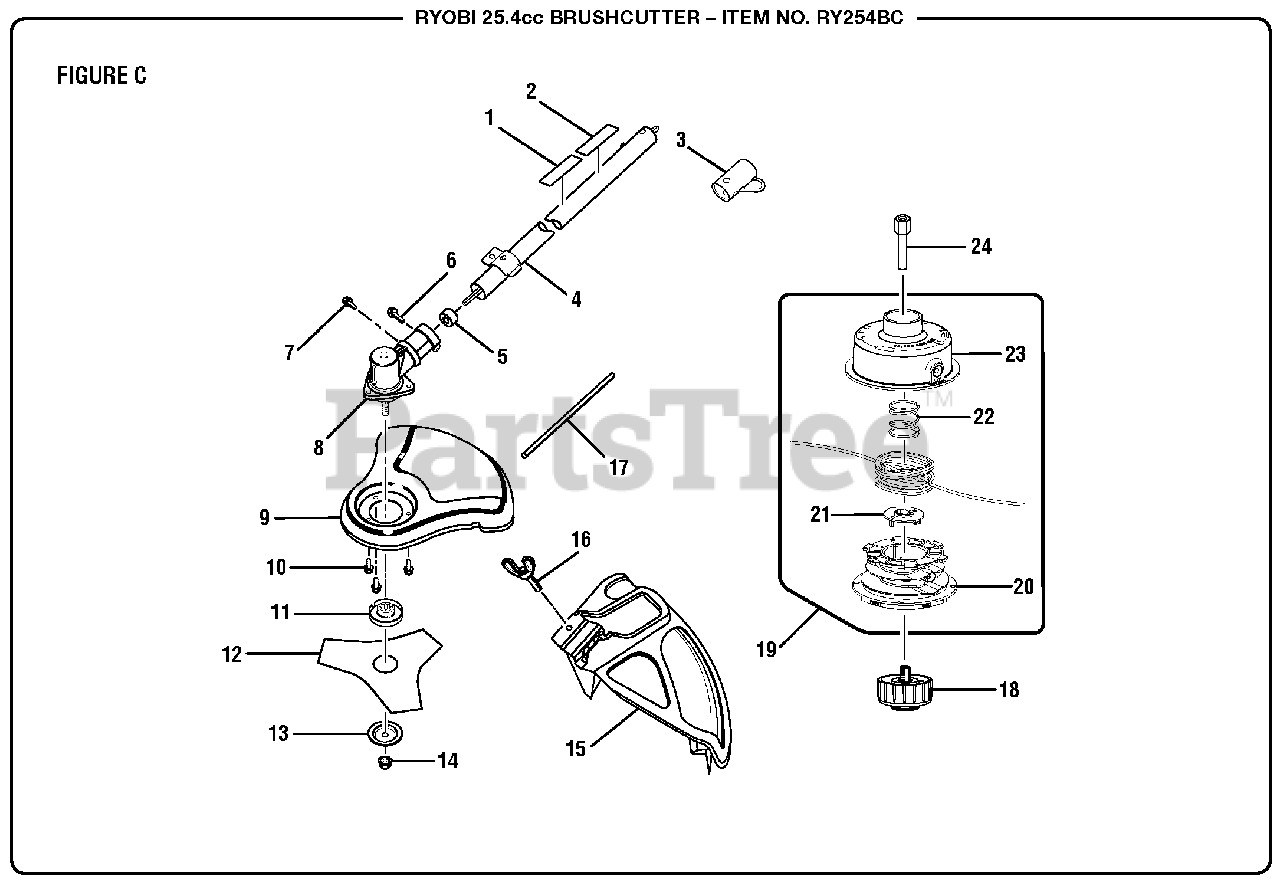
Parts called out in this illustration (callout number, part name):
1	Expand-it Label
2	Brushcutter Safety Label
3	Storage Hanger Cap
4	Lower Straight Shaft Boom Assembly
6	Screw (1/4-20 x 1-1/4 in., Hex Washer Hd. S.T.)
7	Screw (10-24 x 5/8 in., Hex Washer Hd. S.T.)
8	Gear Case Assembly
9	Brushcutter Guard
10	Screw w/Washer (10-24 x 1/2 in., Slotted Hex Hd.)
11	Flanged Washer
13	Cupped Washer
14	Lock Nut (M8 x 1.25 in., Left Hand Threads)
15	Grass Deflector Assembly
16	Screw (1/4-20 x 7/8 in.)
17	Gear Head Locking Tool
18	Bump Knob (Red)
19	Trimmer Head Assembly (.095)
20	Spool Assembly
21	String Guide
22	Compression Spring
23	Housing and Eyelet Assembly
24	Trimmer Head Shaft Adaptor
